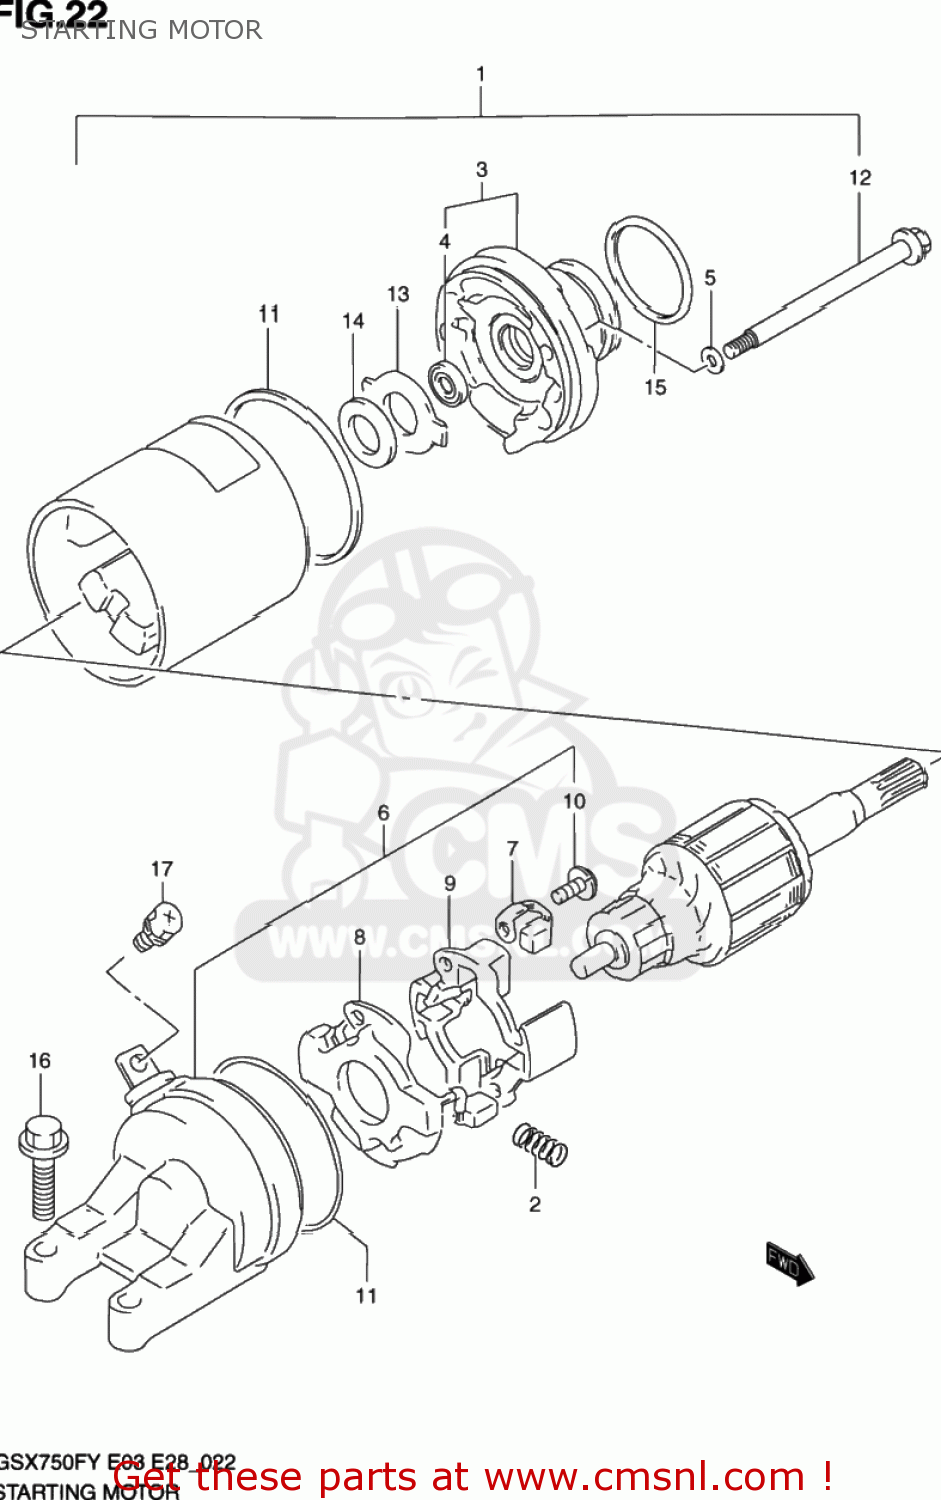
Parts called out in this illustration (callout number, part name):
1	MOTOR ASSY,STARTING
2	SPRING
3	BRACKET
4	SEAL,OIL
5	O RING
6	FRAME ASSY,COMMUTATOR
7	BRUSH
8	BRUSH SUB ASSY,STARTER
9	HOLDER,BRUSH
10	SCREW
11	O RING
12	BOLT
13	PLATE,LOCK
14	SHIM
15	O RING(D:3,ID:24.5)
16	SCREW (6X25)
17	SCREW(5X8)
